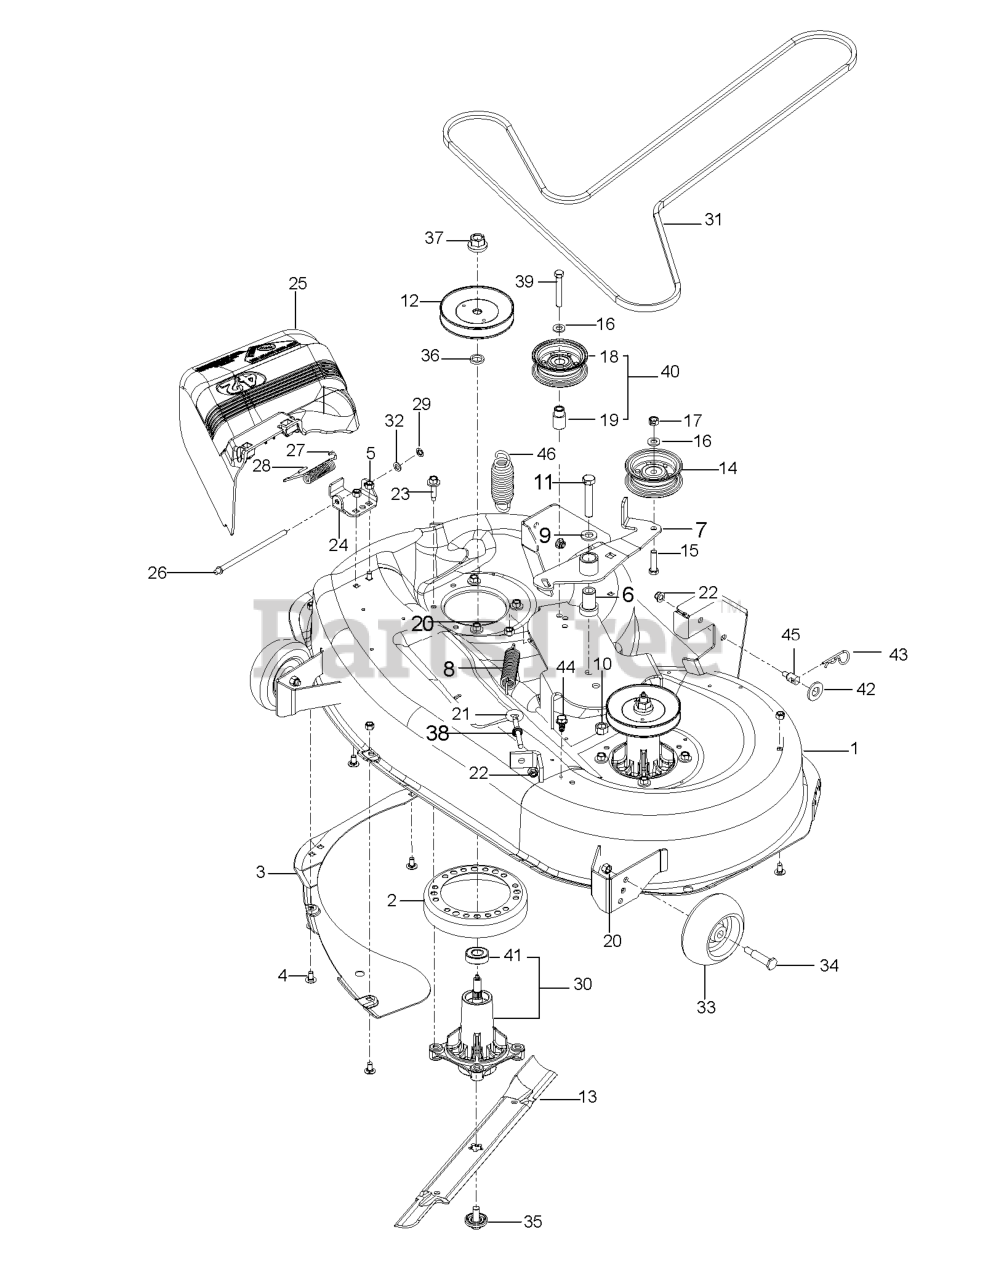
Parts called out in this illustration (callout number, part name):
1	DECK W/DECALS - RZ42 ORANGE
2	STRIPPER-ROUND-UNIVERSAL
3	BAFFLE VORTEX 42
4	CARRIAGE BOLT 5/16C X 5/8"
5	NUT 5/16 NYLOC
6	IDLER SPINDLE
7	DECK IDLER ARM WELDMENT
9	WASHER 1/2" FLAT
10	NUT 1/2-13 HEX NYLOC ZD
11	HCS 1/2C X 2 3/4
12	PULLEY, MANDREL
13	BLADE.42".MULCH
14	PULLEY, IDLER, SHORT
15	HCS 3/8C X 1 1/2
16	WASHER 3/8 SAE FLAT
17	NUT 3/8C CENTERBLOCK
18	PULLEY, IDLER
19	BEARING INSERT
20	NUT 3/8-16 NYLOC
21	EYE BOLT 5/16 X 3.50
22	5/16-18 NYLOC FLANGE NUT
23	WASHER HEAD SCREW
24	BRKT.DEFLECTOR.38"2005+
25	DEFLECTOR 42
26	ROD, HINGE
27	SPRING, TORSION DEFLECTOR
28	CAP-SLEEVE
29	PUSH NUT
30	MANDREL GREASABLE
31	BELT, DECK, 113"
32	WASHER, 11/32 X 5/8 X 16 GA
33	WHEEL GUAGE
34	BOLT, SHOULDER
35	BOLT.WASHER.ASM.7/16-2
36	WASHER-SPACER
37	LOCKNUT - 9/16
38	NUT 5/16C WHIZ
39	HCS 3/8C X 2 1/2
40	IDLER PULLEY ASM
41	BEARING, BALL
42	WASHER 5/8 FLAT
43	HAIRPIN #4
44	SCREW, 3/8-16 X 3/4 THREAD CUT
45	STUD.FASTNER.W/ANTI-ROTATE
